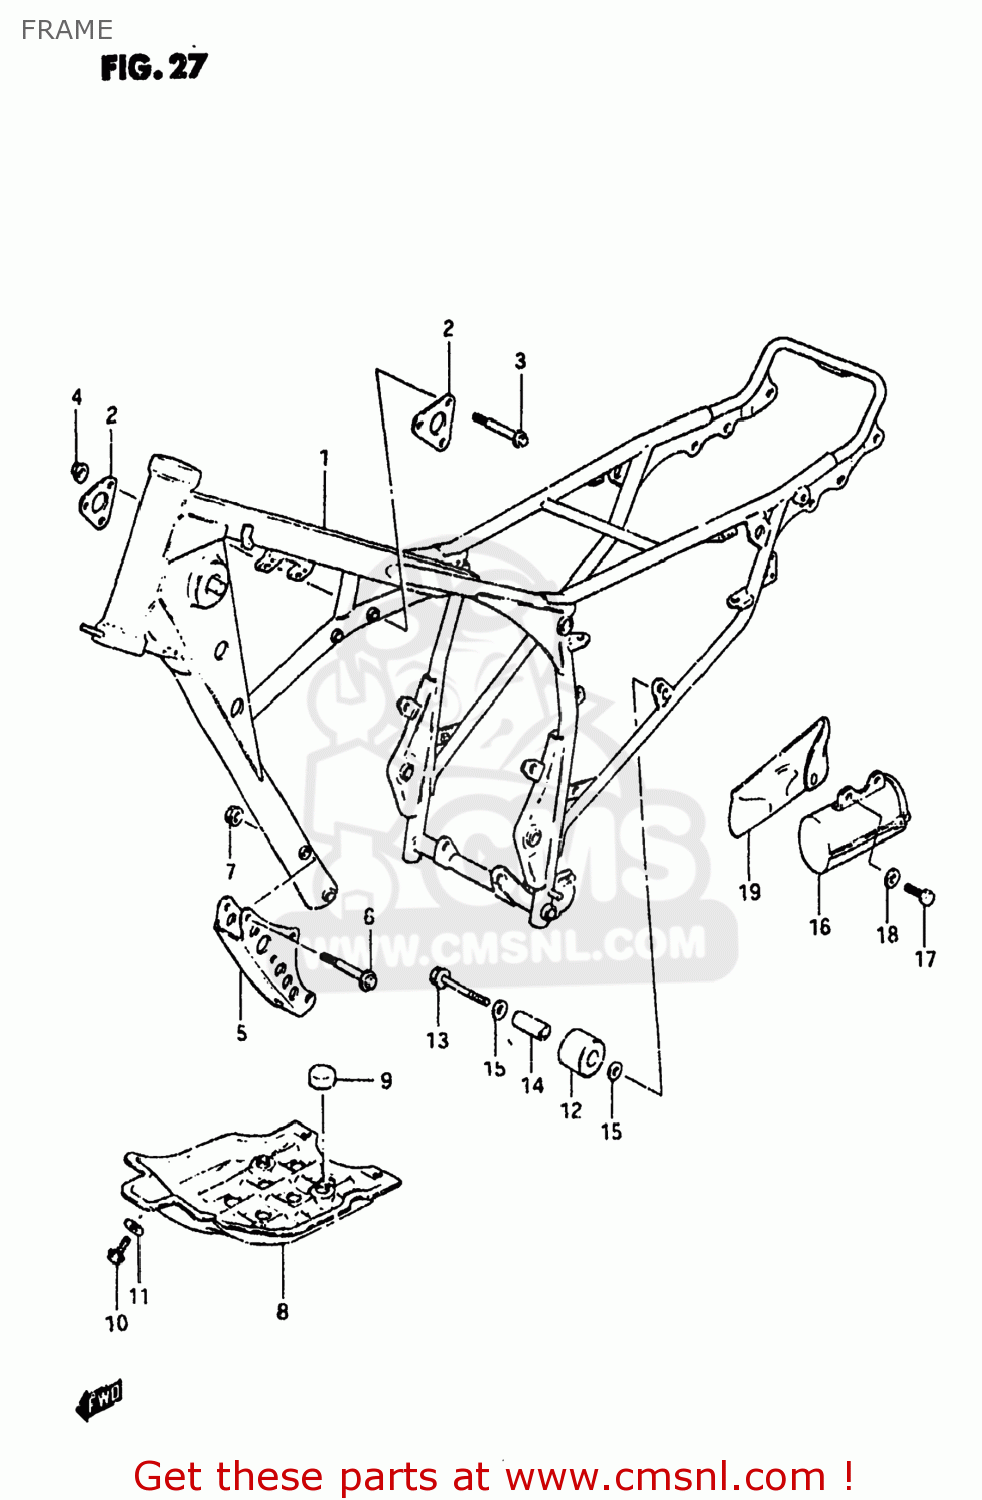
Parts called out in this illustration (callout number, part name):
1	FRAME
2	PLATE,ENGINE MOUNT UPR
3	BOLT
4	NUT
5	PLATE,ENGINE MOUNTING
6	BOLT
7	NUT
8	PROTECTOR,ENGINE
9	CUSHION
10	BOLT
11	WASHER
12	ROLLER,CHAIN LENGTH CONTROL
13	BOLT(8X45)
14	SPACER,CHAIN LENGTH ROLLER
15	WASHER
16	HOLDER,TOOL
17	BOLT, UPPER
18	WASHER (6.5X18X1.6)
19	TOOL ASSY
